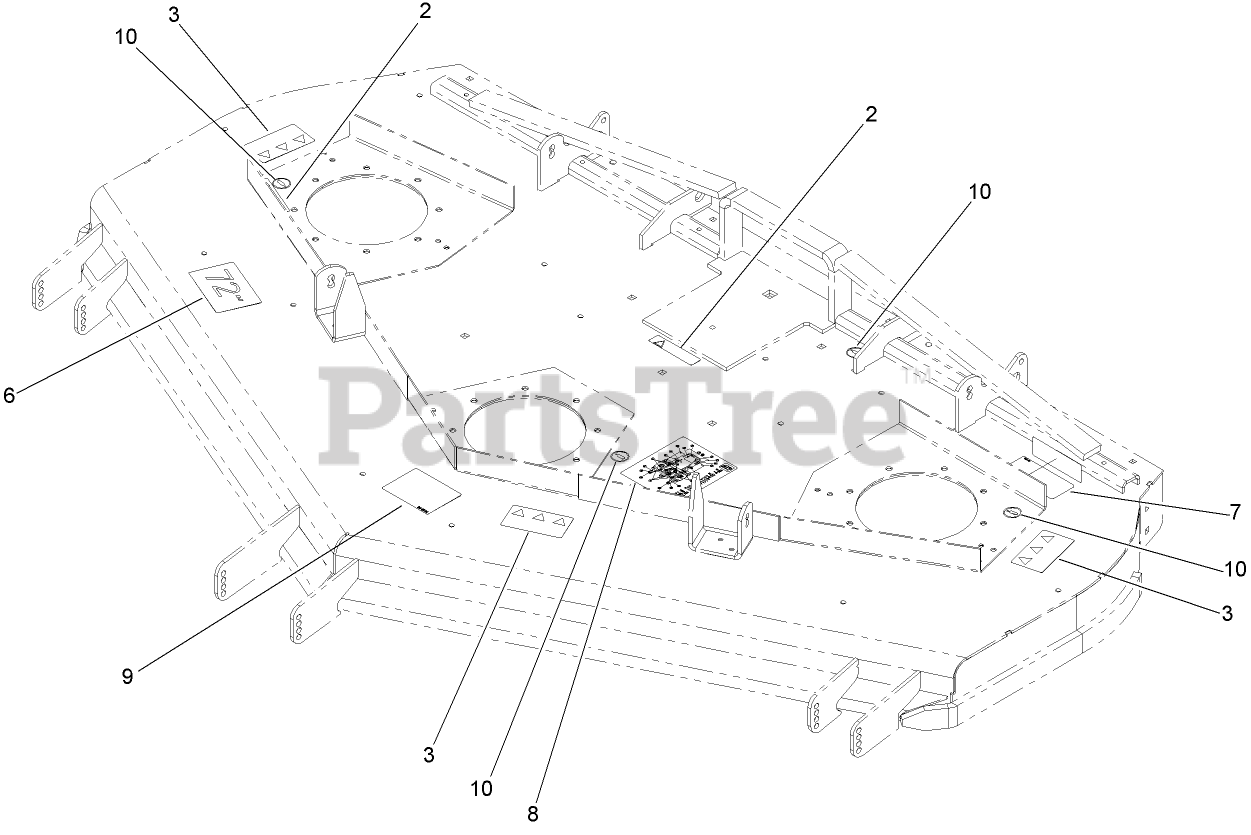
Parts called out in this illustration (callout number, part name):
2	DECAL-WARNING
3	DECAL-DANGER
6	DECAL
7	DECAL-TORQUE, BLADE BOLT
8	DECAL-SERVICE AID, BELT ROUTING CE
9	DECAL-ANTI SCALP
10	DECAL-GREASE
